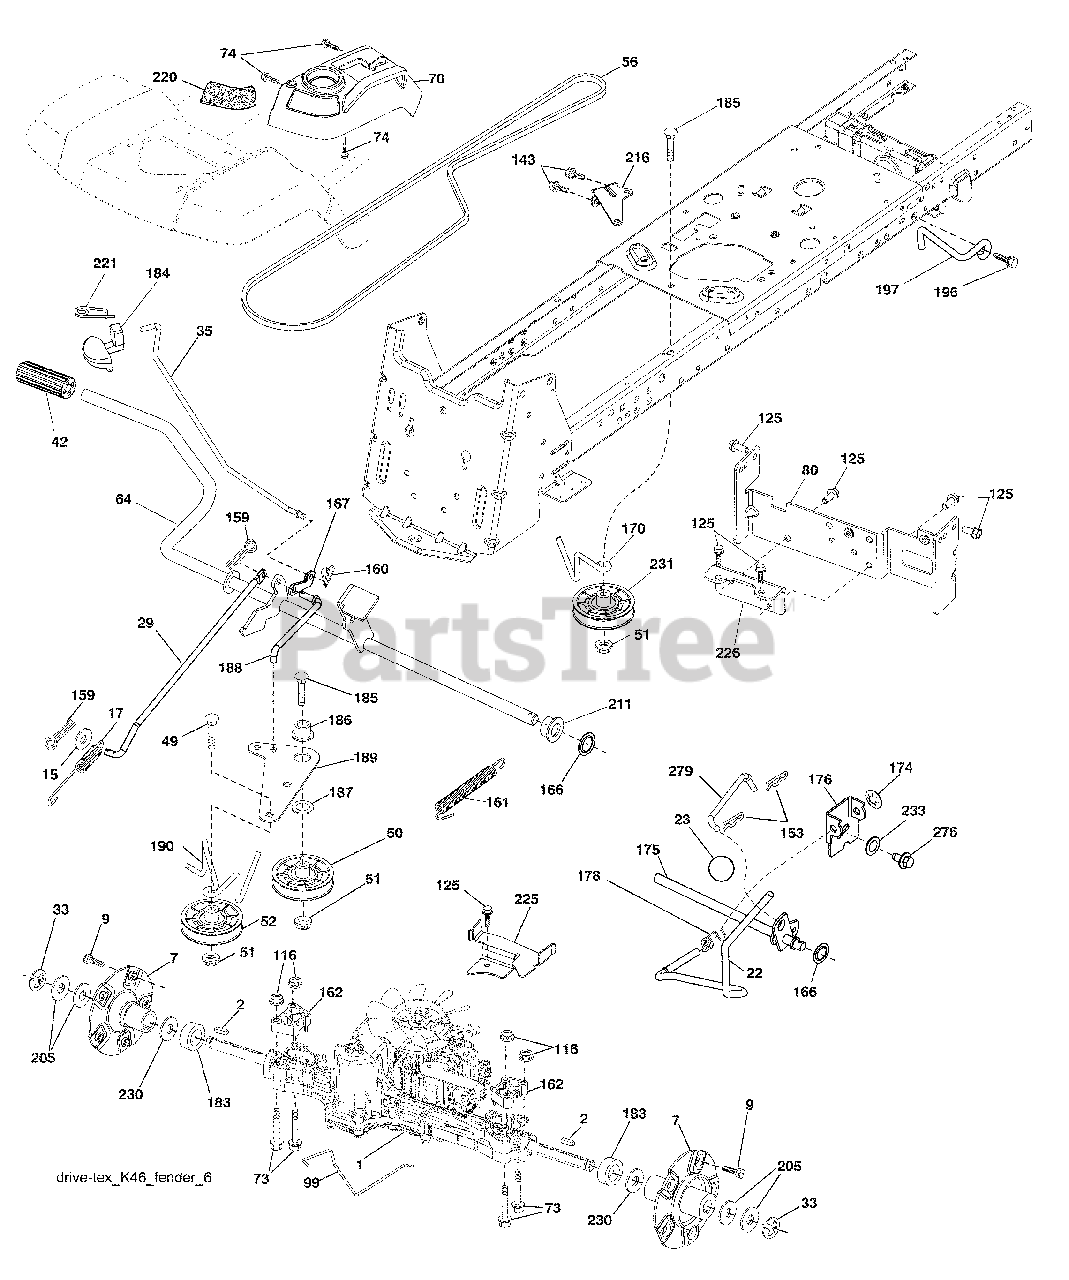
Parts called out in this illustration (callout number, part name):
1	Transaxle, TUFFTORQ K46 AW
7	Hub Asm. Wheel Rear 22" TX GT .06
9	Bolt Hub Wheel Rear
15	Washer 13/32 x 13/16 x 16 Ga.
17	Spring Brake
29	Rod, Brake
35	Rod Brake Park
42	Cover Foot Pedal
50	Pulley Idler Flat
51	Lock Nut 3/8-16
52	Idler V-Groove 910" Offset
56	V-Belt Drive
64	Shaft Asm. Pedal Brake Control
70	Console Asm.
73	Bolt Hex Flghd 5/16-18 Gr. 5
74	Screw 1/4 x 1/2
80	Strap Torque
99	Rod Bypass
116	Nut Lock Hex Flange 5/16-18
125	Screw 5/16-18 x 3/4
143	Screw 5/16-18 x 1/2
153	Retainer Spring
159	Pin Cotter 1/8 x 3/4
160	Retainer Clip
161	Spring Return Clutch
162	Spacer Transaxle 18 and 22
166	Nut Push
167	Latch Brake Parking
170	Keeper Belt Centerspan
175	Shaft Asm Shift
176	Arm Clevis Rod Shift
178	Spring Shift
183	Spacer Split
184	Handle Parking Brake
185	Bolt Rdhd Sqnk 3/8-16 x 2-3/4 Gr. 5
186	Spacer Retainer
187	Washer
188	Link Clutch Ground Drive
189	Bellcrank Ground Drive
190	Keeper Bellcrank Ground Drive
196	Screw 3/8-16 x 1
197	Link Clutch Anti-Rotation
211	Bushing Brake Shaft
216	Bracket Pulley Idler
220	Reflector RH
221	Retainer Spring Clip Handle
225	Keeper Belt Trans.
226	Bracket Mount Torque
230	Washer Hardened
231	Idler V-Groove 1.688" Offset
233	Washer Serrated
276	Bolt 7/16-14 x 1 Gr. 5
279	Link Shift
282	Spacer Split .800 X .350 22" T
